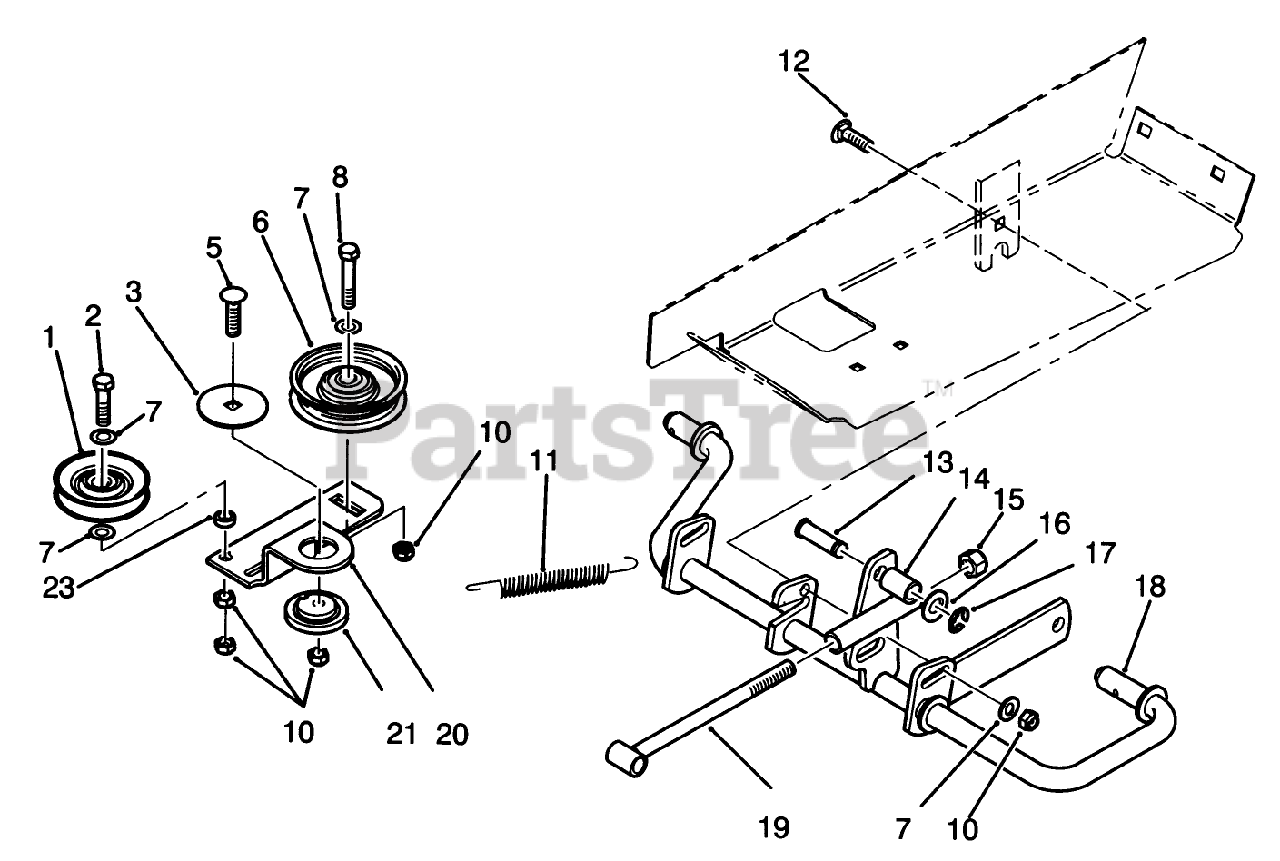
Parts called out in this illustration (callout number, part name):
2	SCREW-HH
3	WASHER-BEARING
5	SCREW-CARR
7	WASHER-FLAT
8	SCREW-HH
10	NUT-LOCK, NI
11	SPRING - CLUTCH
12	BOLT-CARR
15	NUT-LOCK, NI
16	WASHER-FLAT
17	RING-RETAINING, EXTERNAL
20	ARM-IDLER
21	BUSHING
